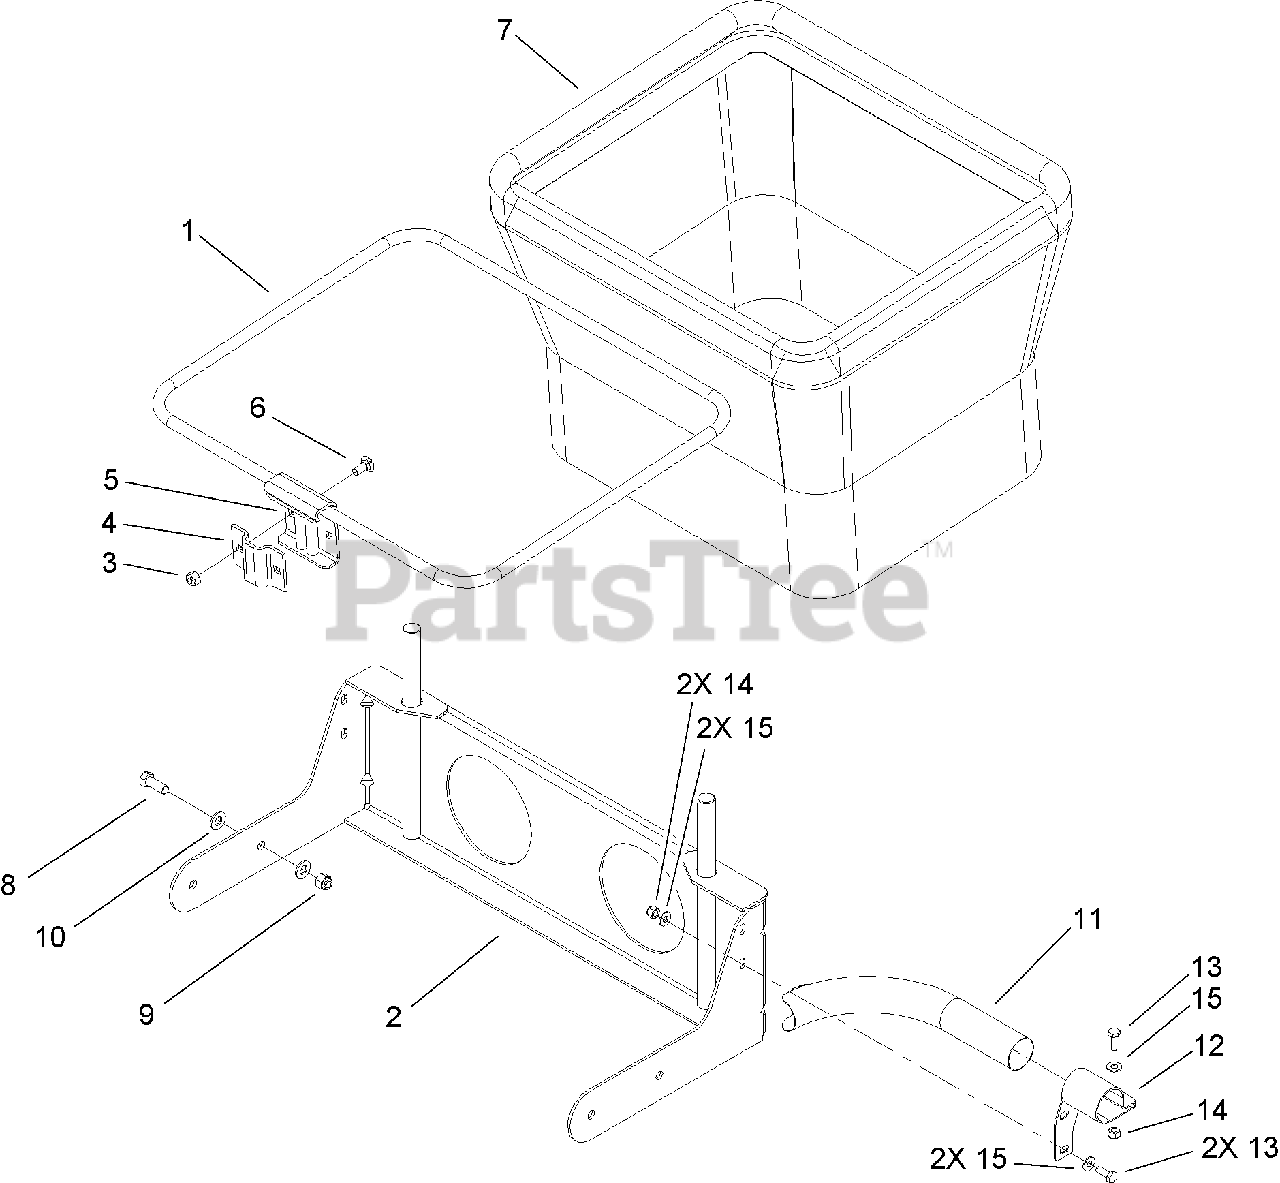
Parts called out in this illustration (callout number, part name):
1	FRAME-BAG
2	BAGGER SUPPORT ASM
3	NUT-LOCK, NI
5	HANGER-BAG
6	BOLT-CARR
8	SCREW-HH
9	NUT-LOCK, NI
10	WASHER-FLAT
11	EXHAUST PIPE ASM
12	BRACKET-EXHAUST
13	SCREW-HH
14	NUT-LOCK, NI
15	WASHER-FLAT
